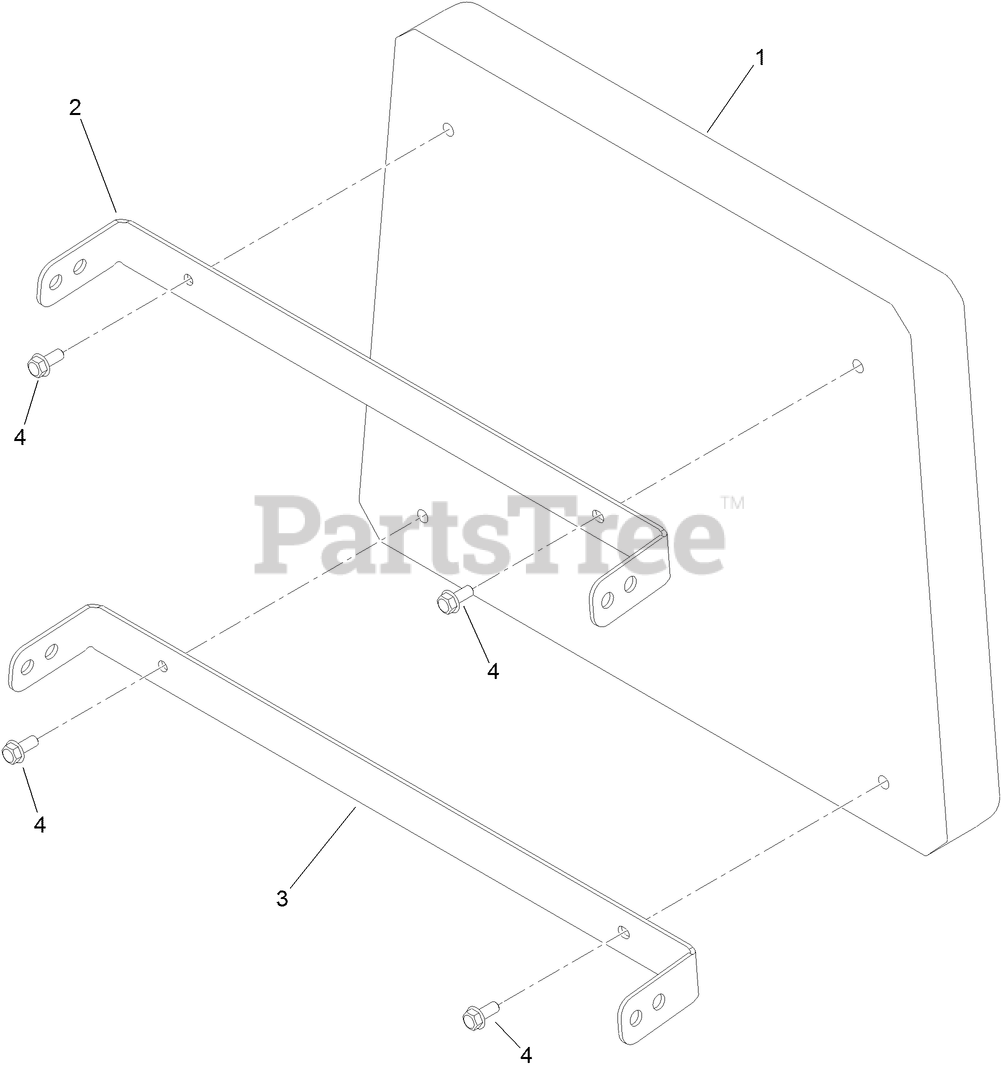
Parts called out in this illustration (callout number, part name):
1	CUSHION-BLACK
2	BRACKET-PAD, UPPER
3	BRACKET-PAD, LOWER
4	SCREW-HHF
